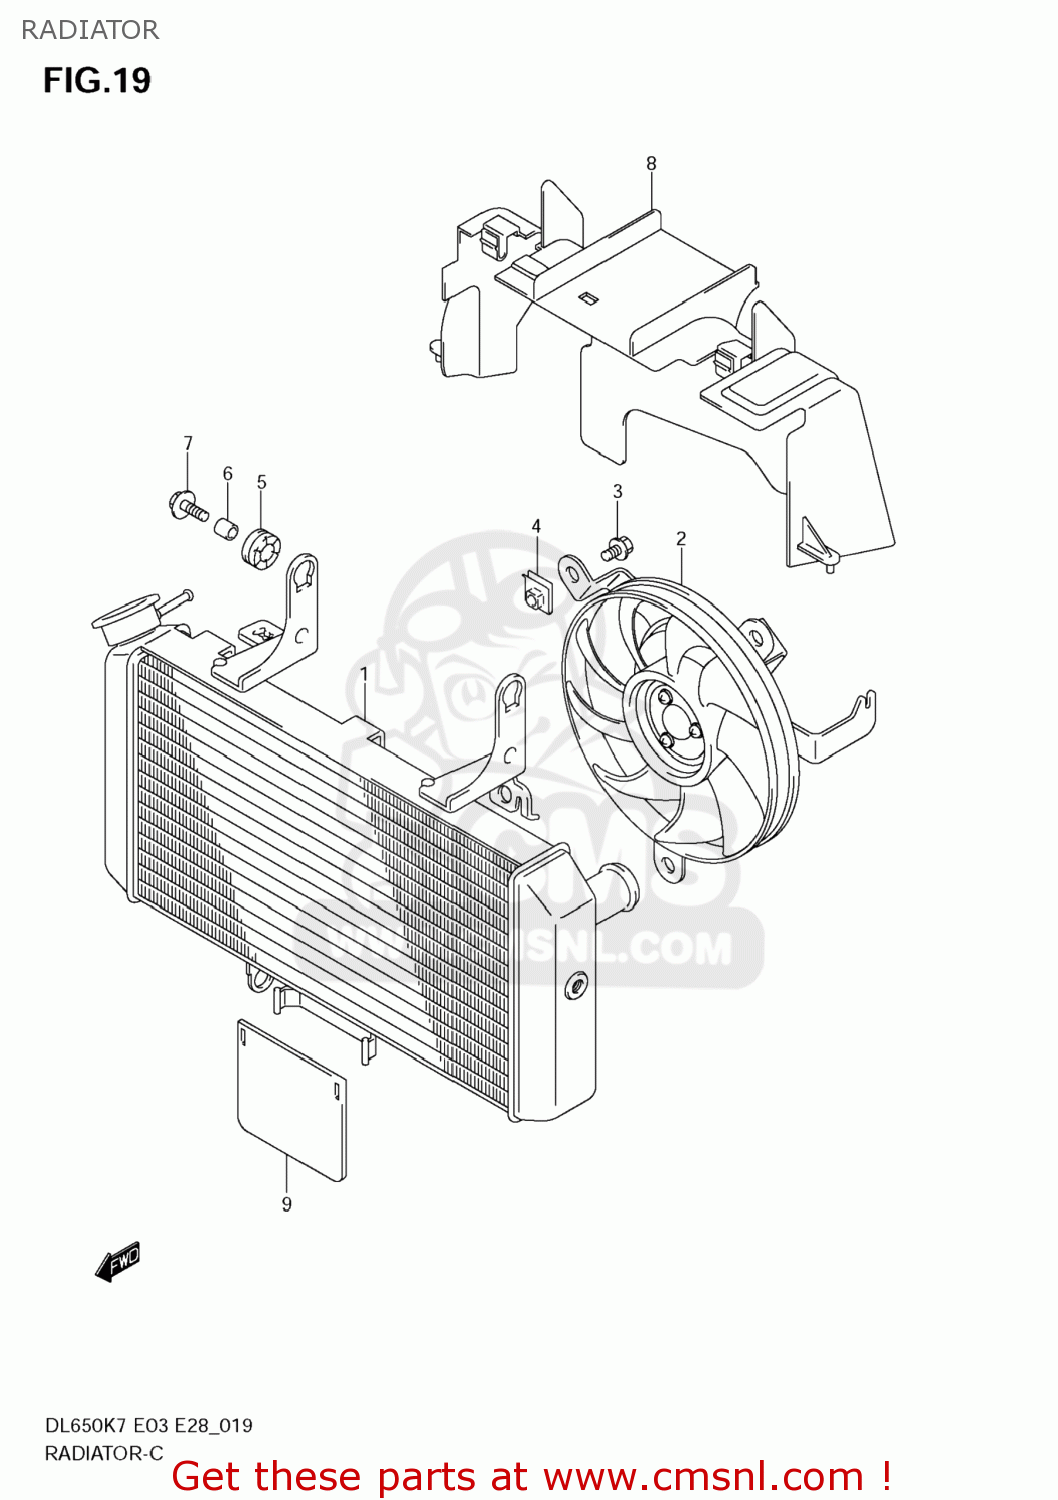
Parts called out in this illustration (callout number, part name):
1	RADIATOR ASSY,WATER
2	FAN ASSY,RADIATOR
3	BOLT,FAN ASSY
4	NUT,FAN ASSY
5	CUSHION
6	SPACER (6.5X10
7	BOLT (6X25)
8	SHIELD,RADIATOR HEAT
9	RUBBER,RADIATOR UNDER
